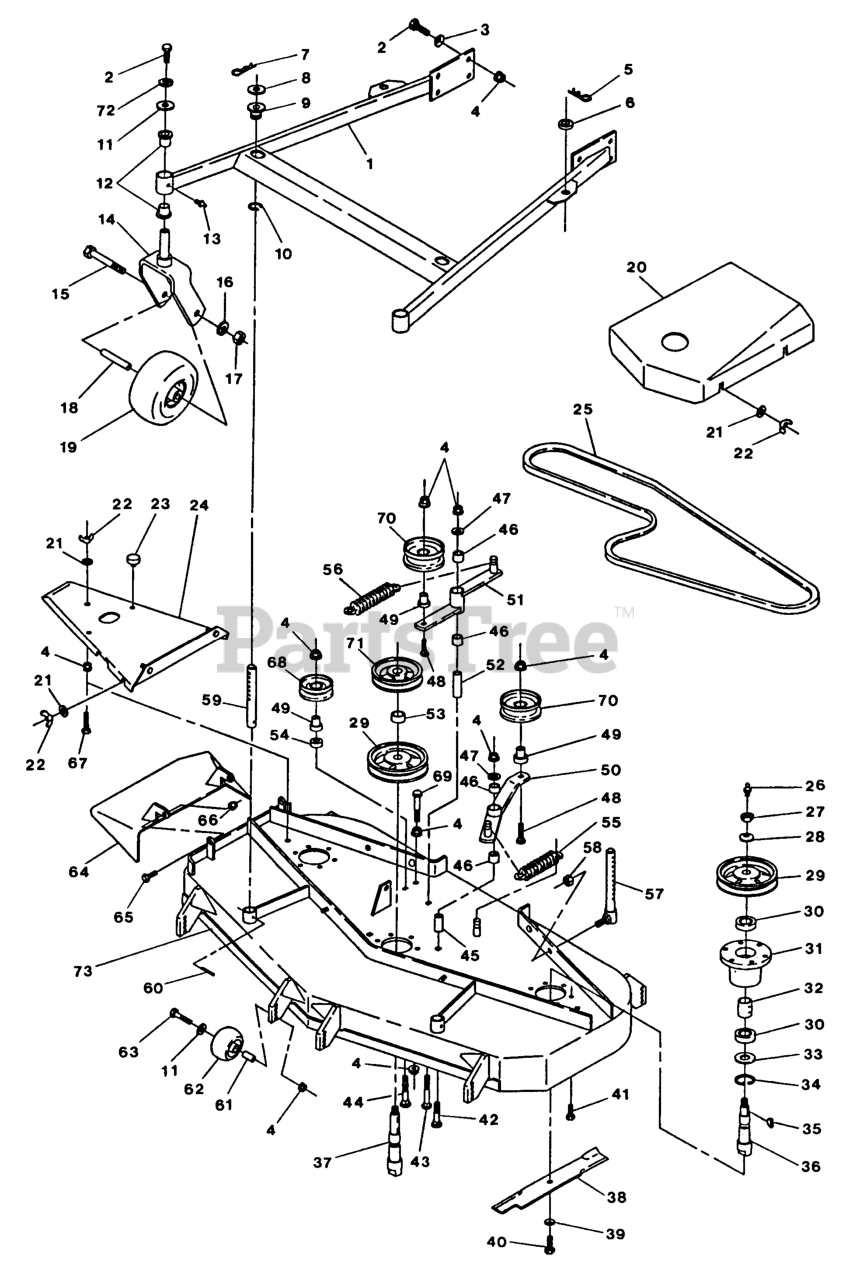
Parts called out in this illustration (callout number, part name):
5	PIN,HAIR COTTER
8	WASHER-FLAT
9	BUSHING-DECK
22	NUT-WING
24	WLD,DECK COVER
25	BELT-DRIVE, BLADE
28	WASHER-SPRING
29	SHEAVE,BLADE DRIVE
32	SPACER,BEARING
33	SEAL,MECHANICAL DUST
34	RING,SNAP WLDS N5000-244
36	SPINDLE-OUTER BLADE
37	SPINDLE-CENTER BLADE
39	WASHER-SPRING
45	BUSHING
46	SLEEVE-BEARING
52	BUSHING-PIVOT, IDLER
55	SPRING-EXTENSION
56	SPRING-EXTENSION
59	ROD,DECK SUPPORT
60	PIN,ROLL
62	ROLLER-SCALP, ANTI
63	SCREW-HH
